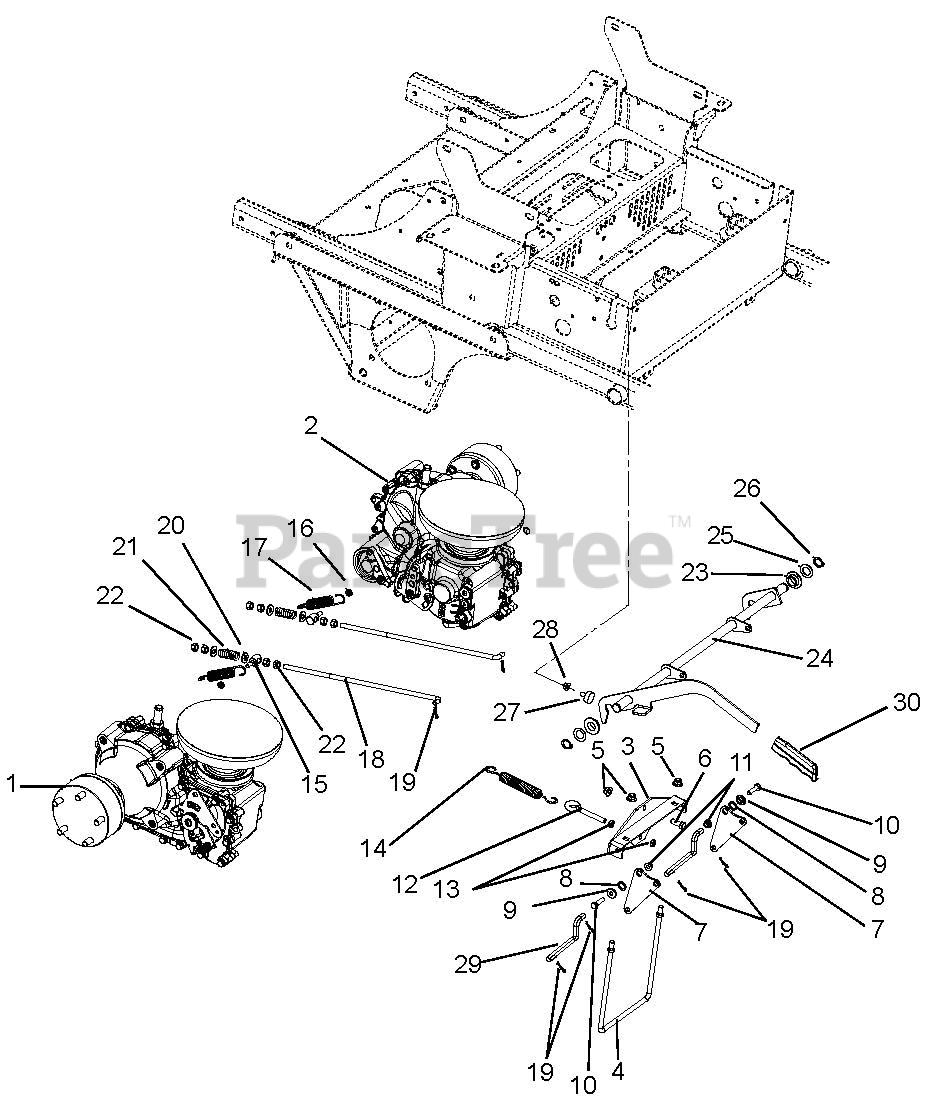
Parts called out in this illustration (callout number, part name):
1	Transmission, Right Hand HG ZT-5400
2	Transmission, Left Hand HG ZT-5400
3	Weldment, Spring Anchor Bracket
4	Rod, Brake Mounting
5	Nut, Locking Nylon Flange .38-16 YWZC
6	Bolt, Hex .38-16 x 1.00 GR5 YWZC
7	Plate, Brake Pivot
8	Wave Washer .531 x .781 x .125FH
9	Bushing, Flange .32 x .500 x .344 x .880
10	Bolt, Hex .31-18 x 1.25 GR5 YWZC
11	Nut, Locking Nylon Flange .31-18 YWZC
12	Bolt, Eye .375-16 x 2.50 YWZC
13	Nut, Hex Jam .375-16 YWZC
14	Spring, Extension
15	Trunnion, .38-16
16	Nut, Locking Center Jam .31-18 YWZC
17	Spring, Tension .105 x .85 x 5.00 WLD 40
18	Rod, Brake Adjustment
19	Pin, Hair
20	Washer, Flat Steel .38 x .875 x .083 YWZC
21	Spring, Compression .142 x .710 x 1.75
22	Nut, Hex .38-16 YWZC
23	Bushing, Flange .762 x 1.48 x .44 NYL
24	Weldment, Brake Interlock
25	Washer, Hardened Thrust .758 x 1.23 x .031
26	Ring, Retaining External .689 x .078
27	Bumper, Rubber
28	Nut, Spin Lock Flange .312-18 YWZC
29	Linkage, Brake Actuating
30	Grip, Parking Brake (Yellow)
